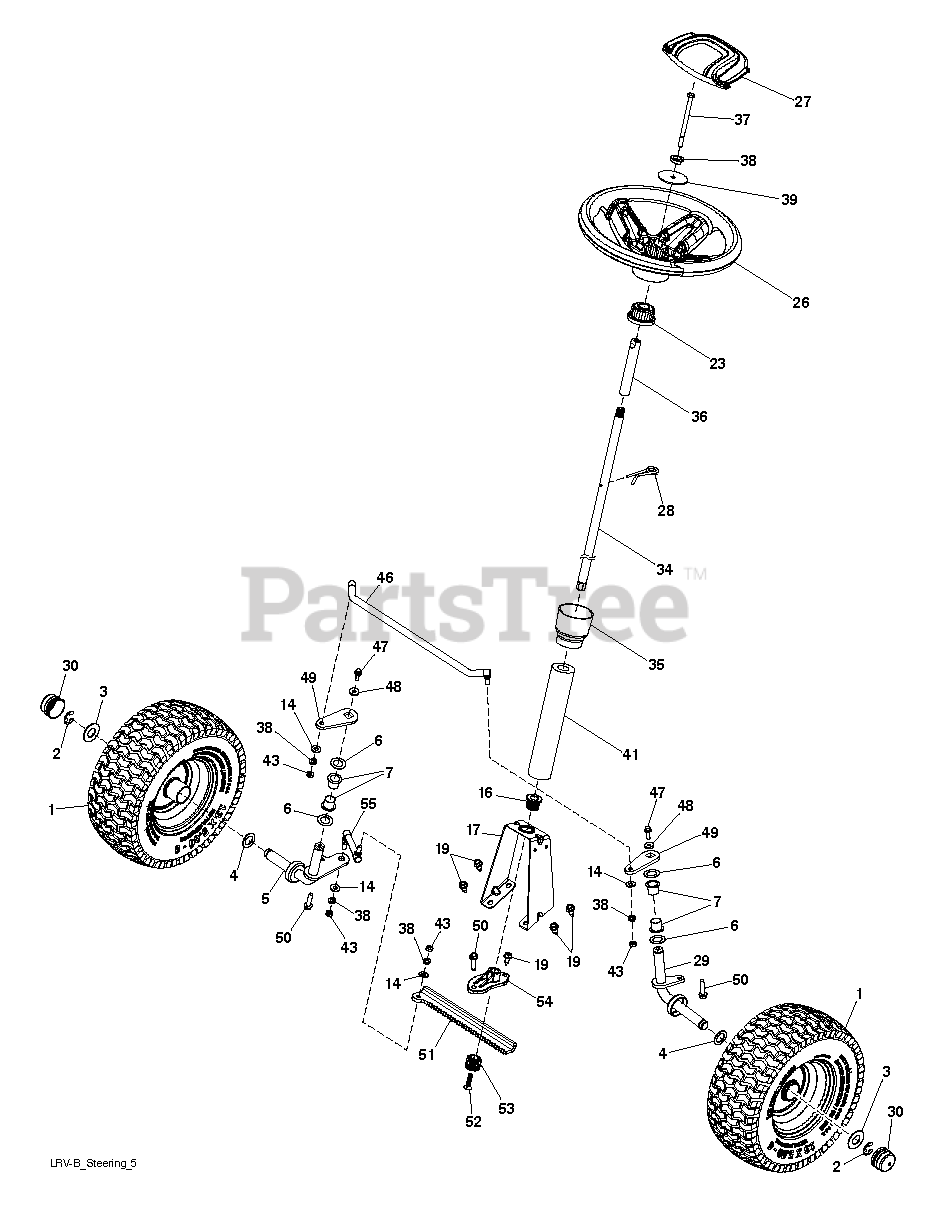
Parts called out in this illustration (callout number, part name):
1	WHEEL.TUBE.13X5.00-6.YELLOW
2	E-RING LT
3	WASHER.HARDENED
5	WELDMENT.SPINDLE.RH.LRV2
7	Steering Column Bearing
14	WASHER M
16	Flanged Bearing, PM 5/8
17	SUPPORT.STEERING.UPPER.LRV2
19	SCREW
23	STEERING.WHEEL.ADAPTER
26	WHEEL.STEERING.MLT.BR.YEL/OVRM
27	CAP.WHL.STRNG.MULTI.BRND.YEL
28	RETAINER.CLIP.SPRING.S
29	WELDMENT.SPINDLE.LH.LRV2
30	CAP.AXLE.FRONT.YELLOW
34	Steering Shaft
35	BOOT.LOWER.STEERING.WHEEL.LRVB
36	SHAFT EXTENSION STEERING
37	BOLT.FIN.HEX.5/16-18
38	LOCKWASHER
39	WASHER.11/32
41	FOAM.SHAFT.STEERING
43	NUT, CROWNLOCK
46	Front Steering Link
47	Flange Screw, Locking.1/4-20.X.75
48	WASHER LT
49	Steering Upper Arm, Pnt
50	SCREW.THDROL.5/16-18X1.25.TYTT
51	Steering Rack Pnt
52	Screw Head Socket Lrvb
54	Steering Support Bushing
55	Drag Link, RH
